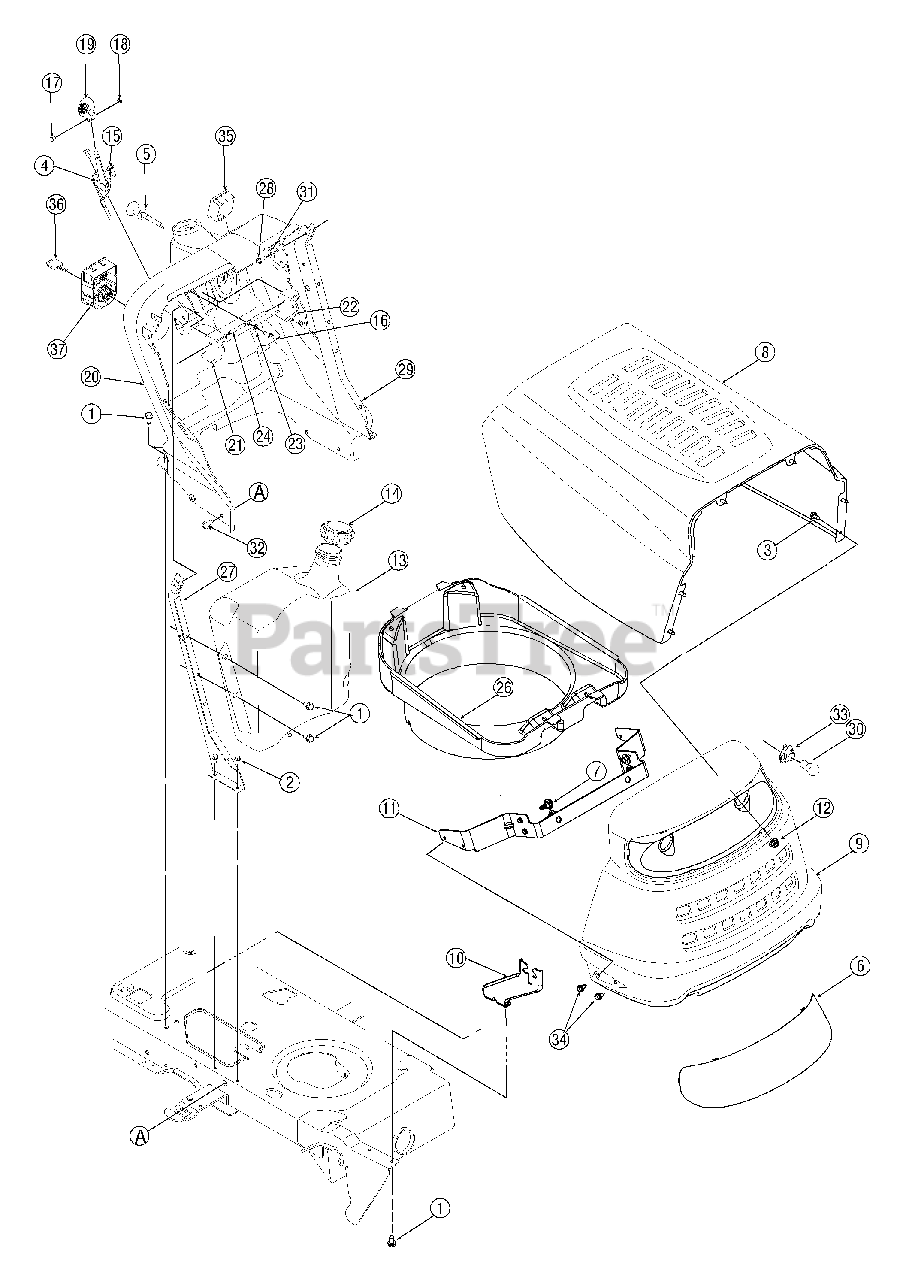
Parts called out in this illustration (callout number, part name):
1	Screw, 5/16-12 x.750
2	Self-tapping Screw, 1/4-20 x.5
3	Hex Cap Screw, 1/4-20 x.62
4	Throttle Control/Cable
5	Choke Knob/Cable
6	Headlight Lens
7	Shoulder Screw,.43 x.29
13	Fuel Tank, Three Gallon
14	Fuel Cap
15	Screw, 1/4-14 x.625
16	Self-tapping Screw, 1/4-15 x.75
17	Truss Phillips Screw, #8-32 x.375
18	Hex Nut, #8-32
19	Throttle Control Knob
20	Dash Panel
21	Cruise Control Button
22	Parking Brake Button
23	Flat Washer, 9/32 x 1/2 x 1/16
24	Brake/Cruise Pivot Rod
26	Hood Plenum
30	Lamp
31	Bell Washer,.265 x.75 x.062
32	Screw, 5/16-18 x.75
33	Headlight Socket
34	Hex Index Screw, 1/4-20 x.625
35	Systems Ind. Monitor w/ Ammeter
36	Ignition Key w/ plastic cover
37	Ignition Switch
